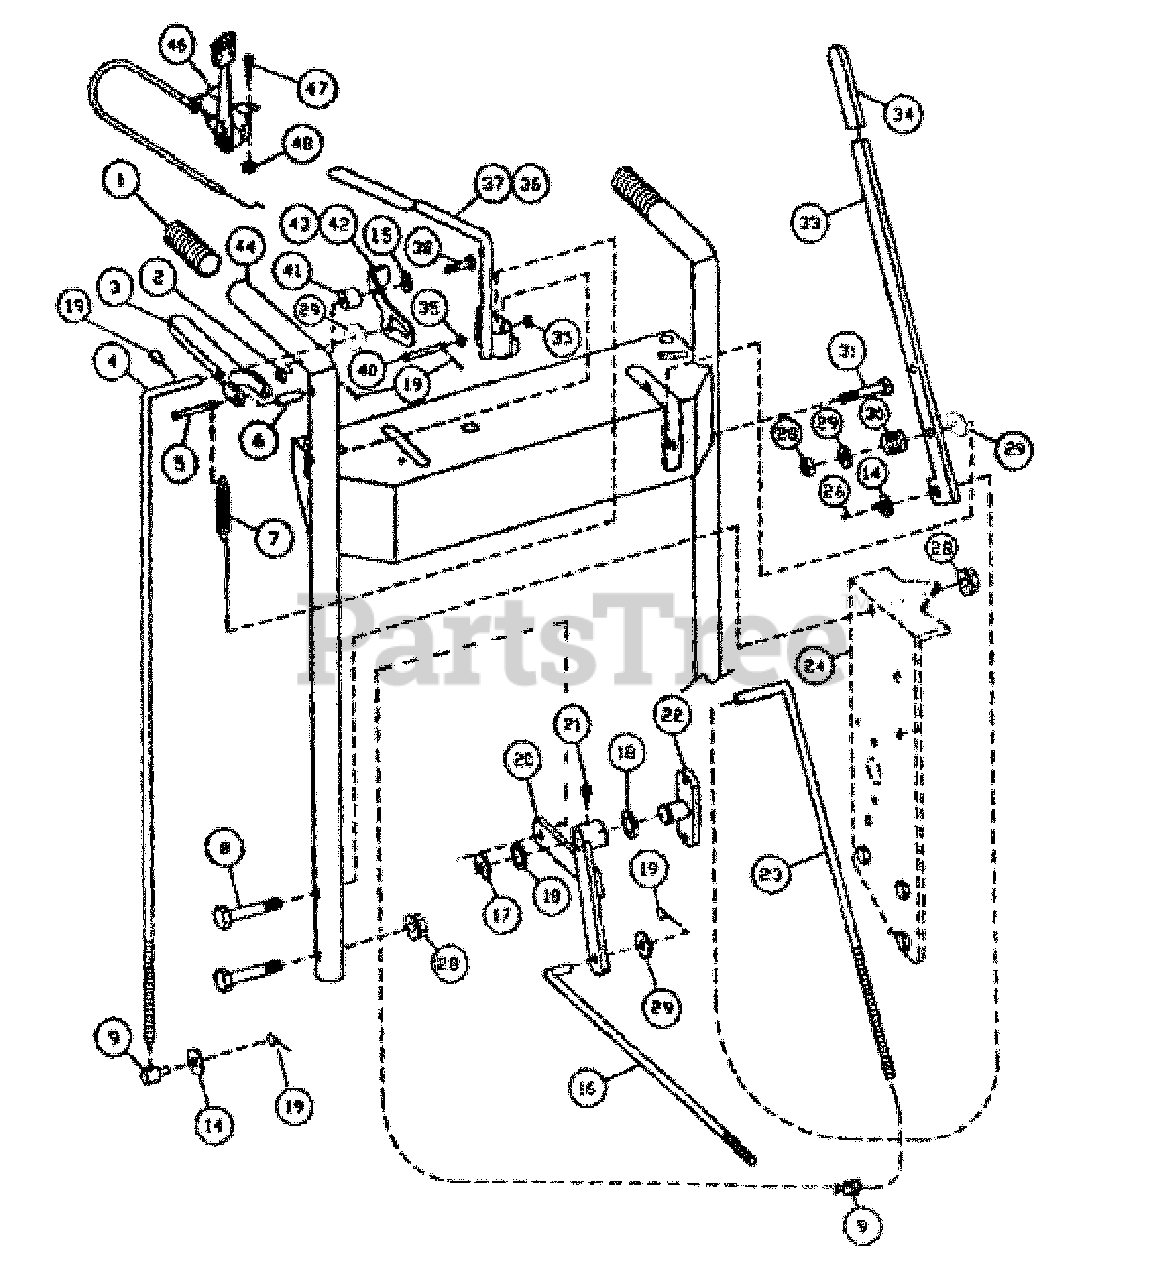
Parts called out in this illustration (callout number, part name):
1	100-072 HANDLE GRIP
2	200-051 NUT M6
3	100-073 TRAC.CONTROL LVR
4	100-074 TRAC. ROD
5	100-075 CLEVIS PIN
6	100-076 ROLL PIN
7	100-077 OPC SPING
8	200-052 HEX BOLT M10`45
9	100-018 SWIVEL
14	5/16STD FLAT WASHER.
17	200-047 SNAP-RING -10 PACK
18	100-120 PLAIN WASHER
19	200-014 COTTER PIN 2`20
21	GREASE FTG (10 PACK) 200-026
22	100-079 BELL CRANK MT.
26	200-054 HAIR PIN COTTER
28	200-006 NYLON NUT M10
29	WASHER, 3/8 STD FLAT
30	100-081 COMP. SPRING
31	200-032 HEX BOLT M10`50
33	100-082 BLADE CONTROLLVR
34	100-045 FLAT GRIP
35	100-083 FLANGE BUSHING
36	100-084 OPC LVR RH
37	100-085 OPC LVR LH
38	200-055&200-058 HEX BOLT
39	200-014 COTTER PIN 2`20
40	100-086 CLEVIS PIN OPC
41	100-087 BUSHING TRACTIO
42	100-088 TRAC LOCK LH
43	100-089 TRAC LOCK GRIP
45	WASHER, 3/16 STD FLAT
46	100-091 THROTTLE CONTROL
47	200-012 BOLT M5`15
